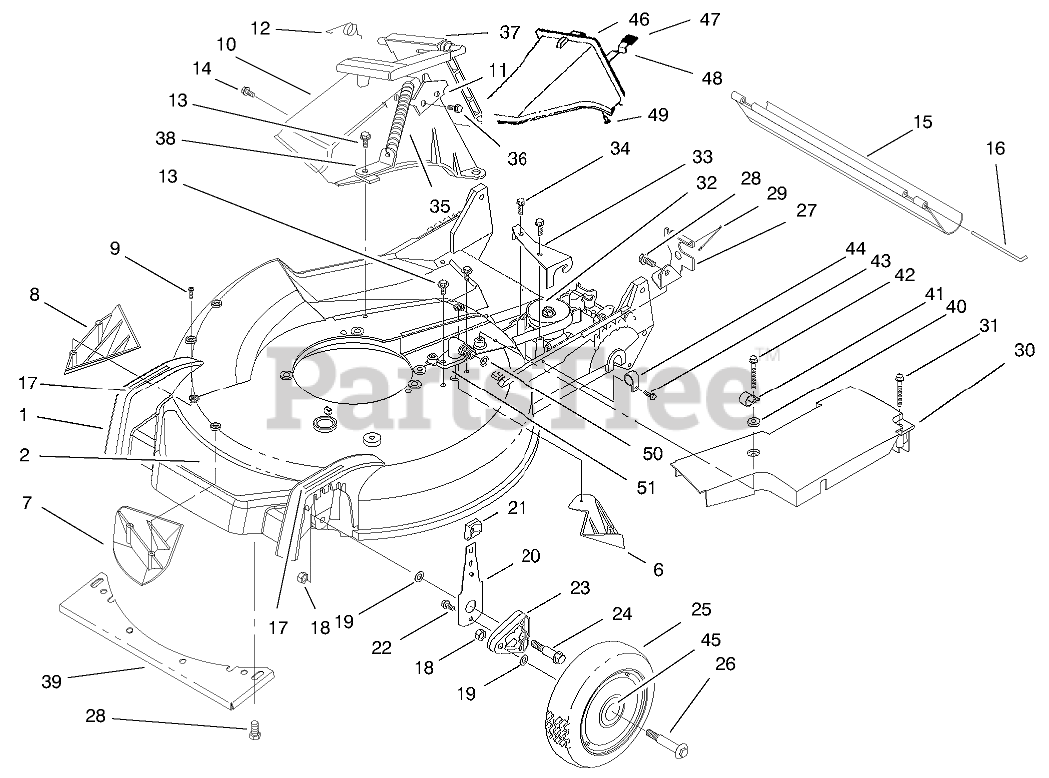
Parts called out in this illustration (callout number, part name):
1	Housing Assembly (Incl. Ref. #6-9,17, 28, 1
2	DECAL - DECK
6	KICKER-REAR
7	KICKER-FRONT
8	KICKER-RH
9	SCREW-PPH
10	TUNNEL-DISCHARGE
11	LATCH-PLATE
12	RETAINER-DOOR
13	SCREW-HWH
14	SCREW AND WASHER ASM
15	SHIELD-TRAILING
16	ROD-SHIELD
17	DECAL - HOC
18	NUT-LOCK
19	WASHER
20	FRONT SPRING ARM ASM
21	KNOB-ARM
22	SCREW-HWH
23	ARM-PIVOT, FRONT
24	BOLT-SHOULDER
25	Wheel-ASM
26	BOLT-WHEEL
27	Bracket-Adj. Trac
28	SCREW-HWHTF
29	RETAINER-CABLE
30	BELT COVER
31	SCREW-HHFTF
32	GEARCASE ASM
33	Bracket-Guide
34	SCREW-HWHTF
35	SPRING-DOOR
36	SCREW-PLASTITE
37	DISCHARGE DOOR ASM
38	BRACKET-SPRING
39	Shield-front
40	WASHER
41	CLAMP-CABLE
42	SCREW-SPECIAL
43	SCREW-HWH
44	CLAMP-CABLE
45	BUSHING
46	DISCHARGE PLUG ASM
47	GRIP-LATCH
48	LATCH-PLUG, DISCHARGE
49	RIVET-HEAD, FLAT
50	O-RING
51	FITTING-WASHOUT
